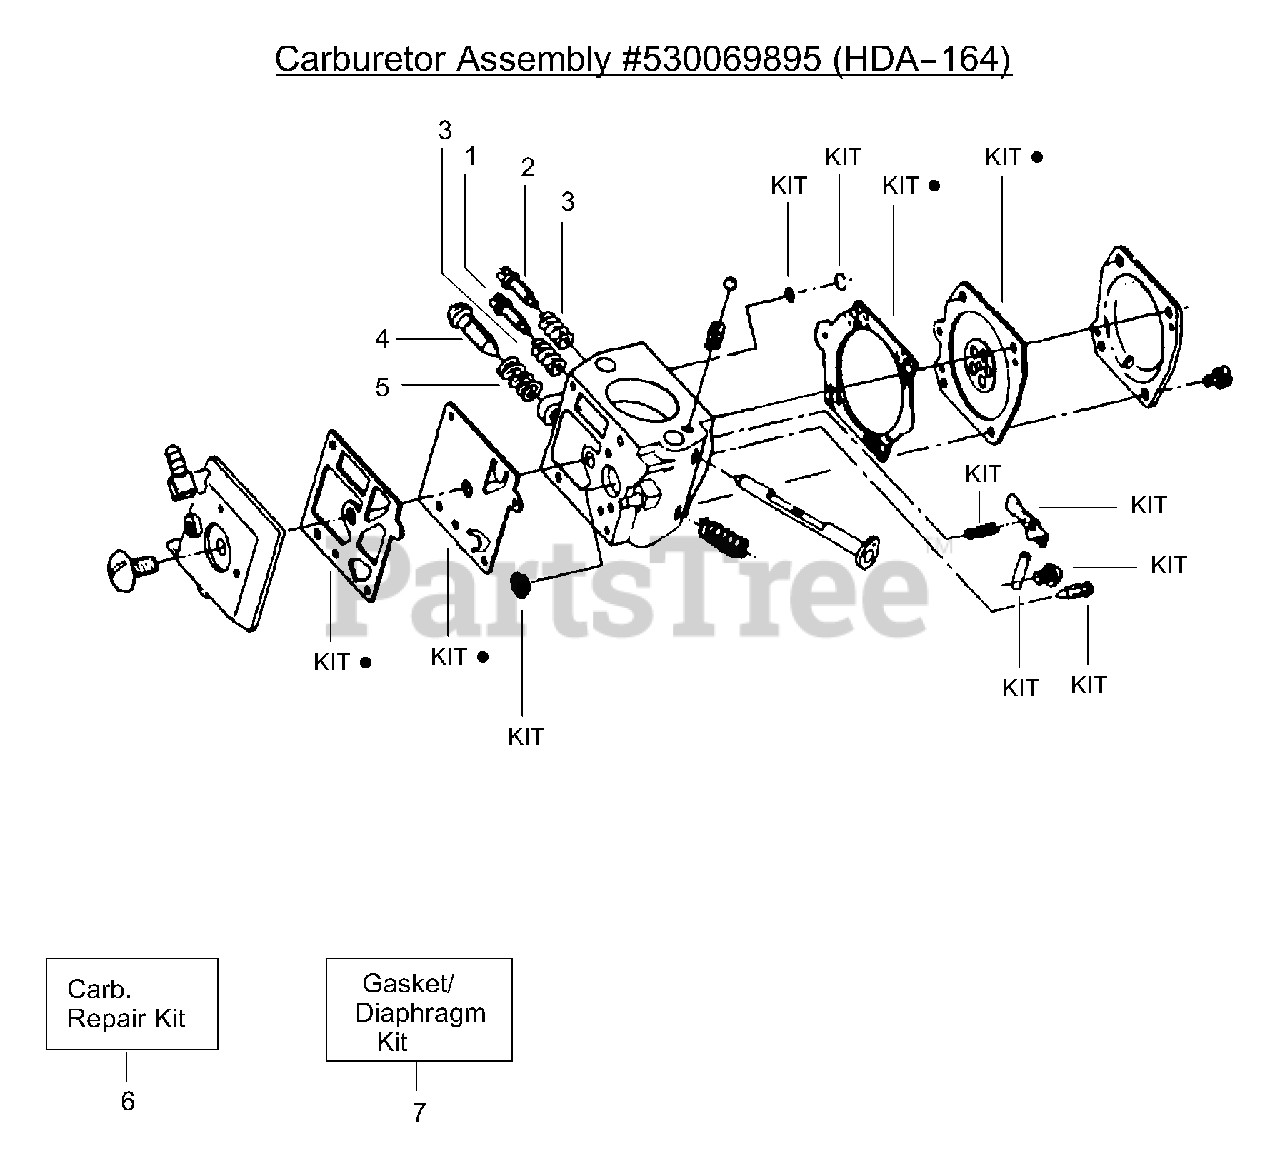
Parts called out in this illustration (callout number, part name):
1	Needle (Low)
2	Needle (High)
3	Needle Adjust Spring
4	Idle Adjust Screw
5	Idle Adjust Spring
6	Carburetor Repair Kit
7	Gasket/Diaphragm Kit
530069895	Carburetor Assembly - HDA164
